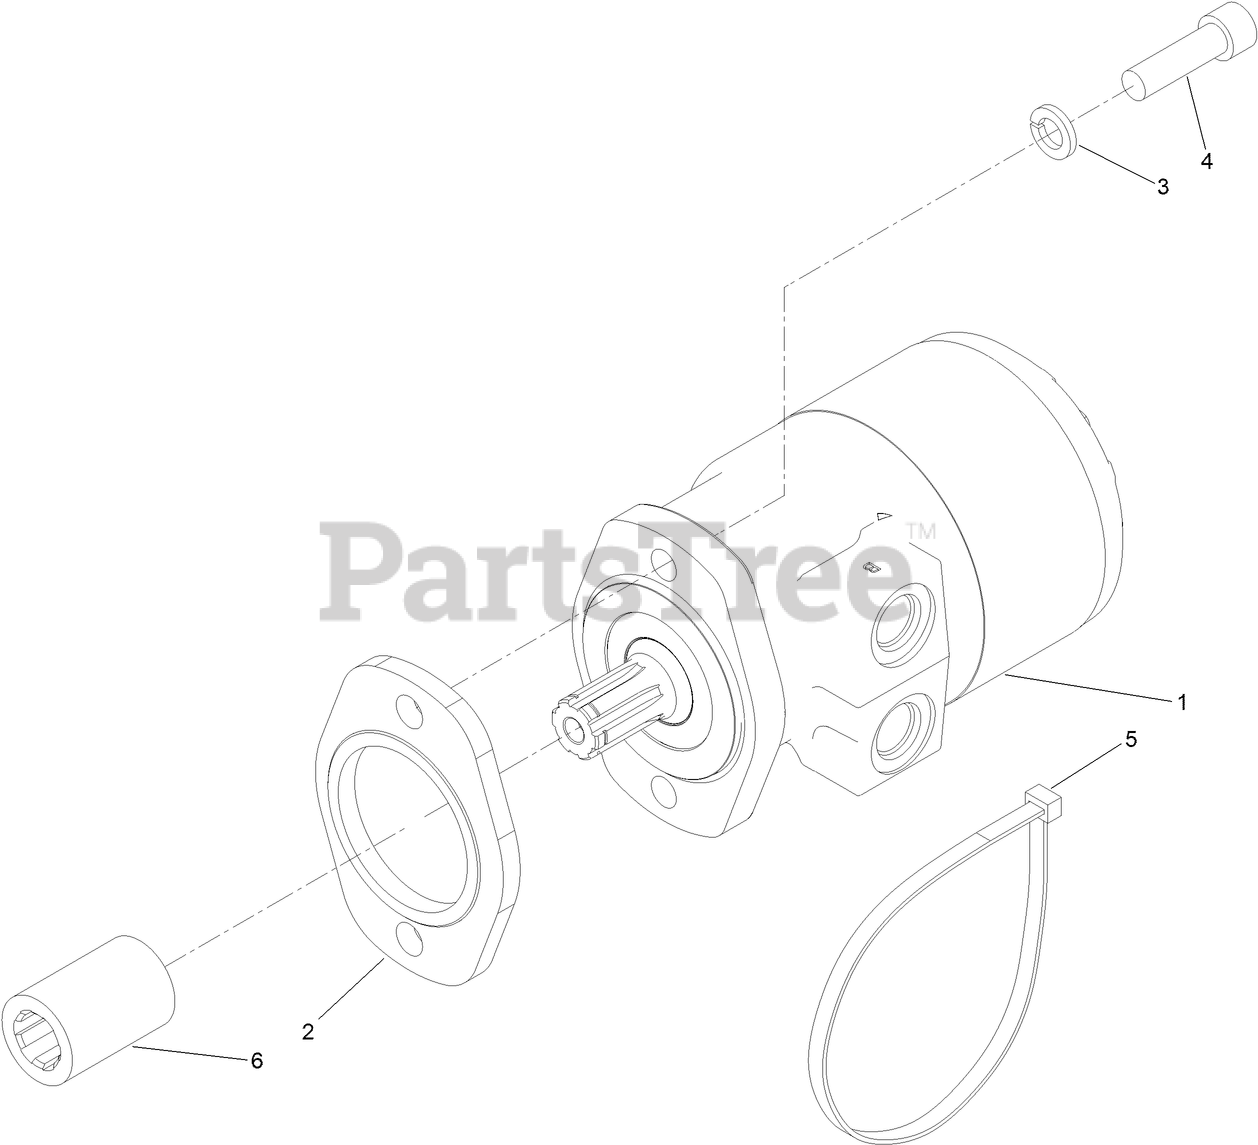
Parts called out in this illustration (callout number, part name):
1	HYD MOTOR ASM
2	PLATE-SPACER
3	WASHER-LOCK
4	SCREW-HSH
5	TIE-CABLE
6	COLLAR-CONNECTING
